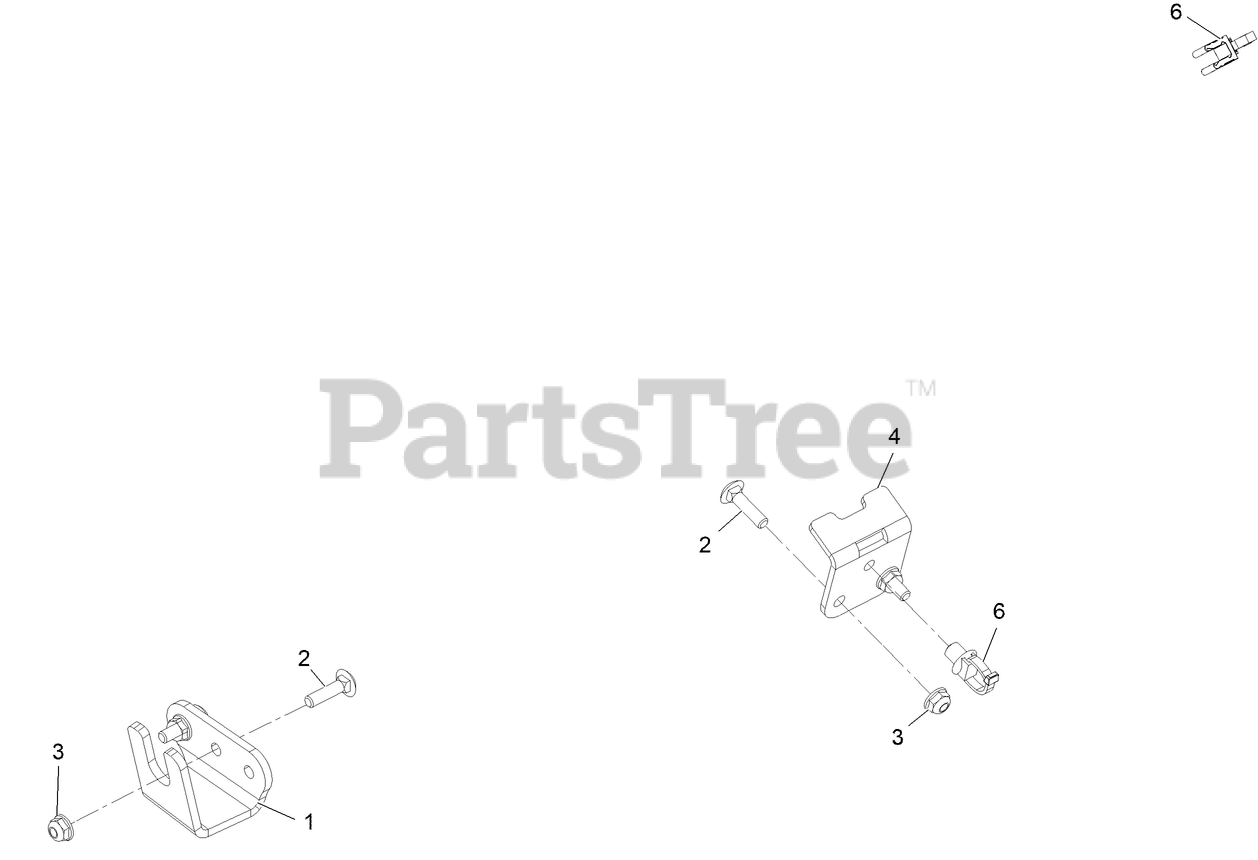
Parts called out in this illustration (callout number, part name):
1	BRKT-OCD CABLE
2	SCREW-CARR
4	BRKT-CABLE
6	CLIP-TIE
